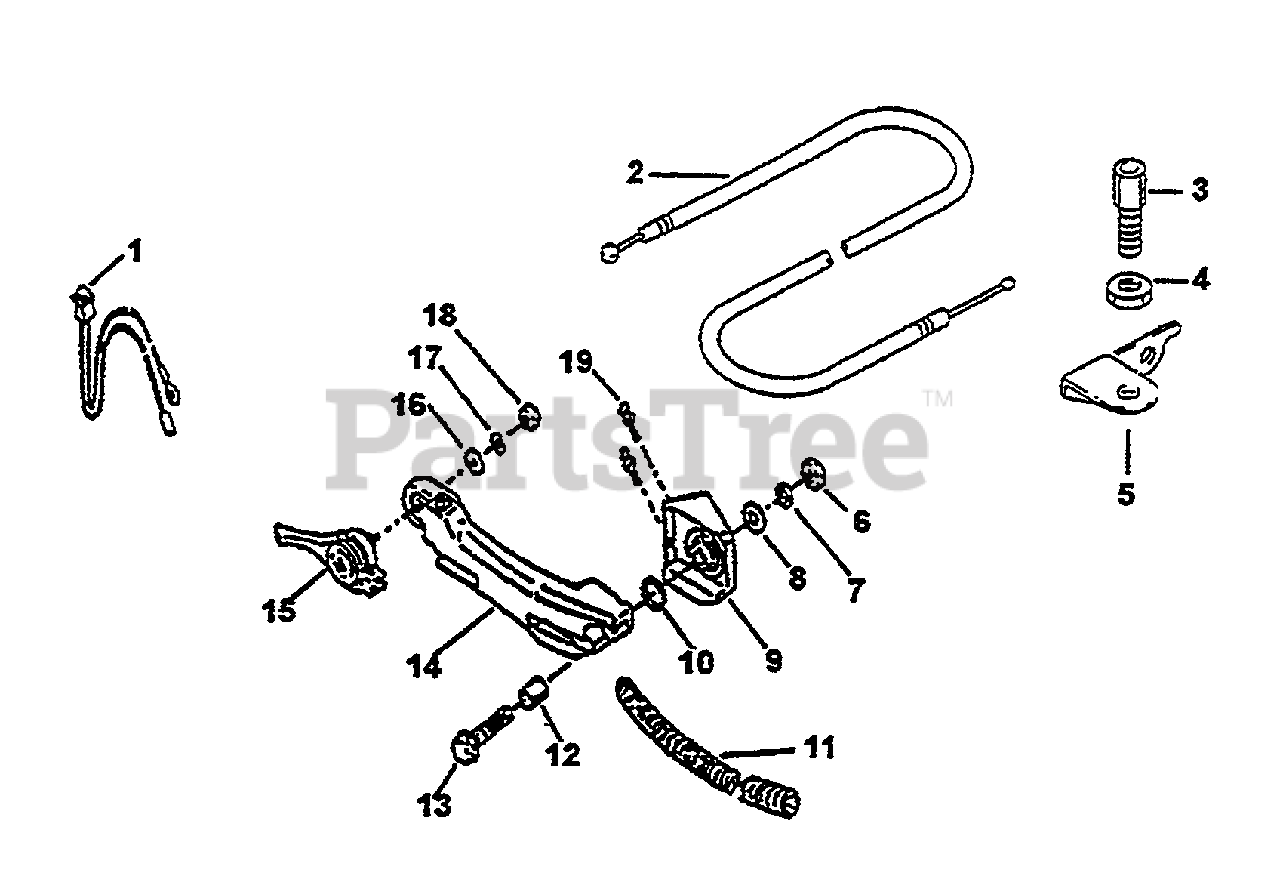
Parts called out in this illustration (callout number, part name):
1	STOP SWITCH
2	THROTTLE CABLE
3	ADJUSTER CABLE
7	WASHER, LOCK
8	WASHER, FLAT
16	WASHER, FLAT
17	WASHER, LOCK
18	NUT
